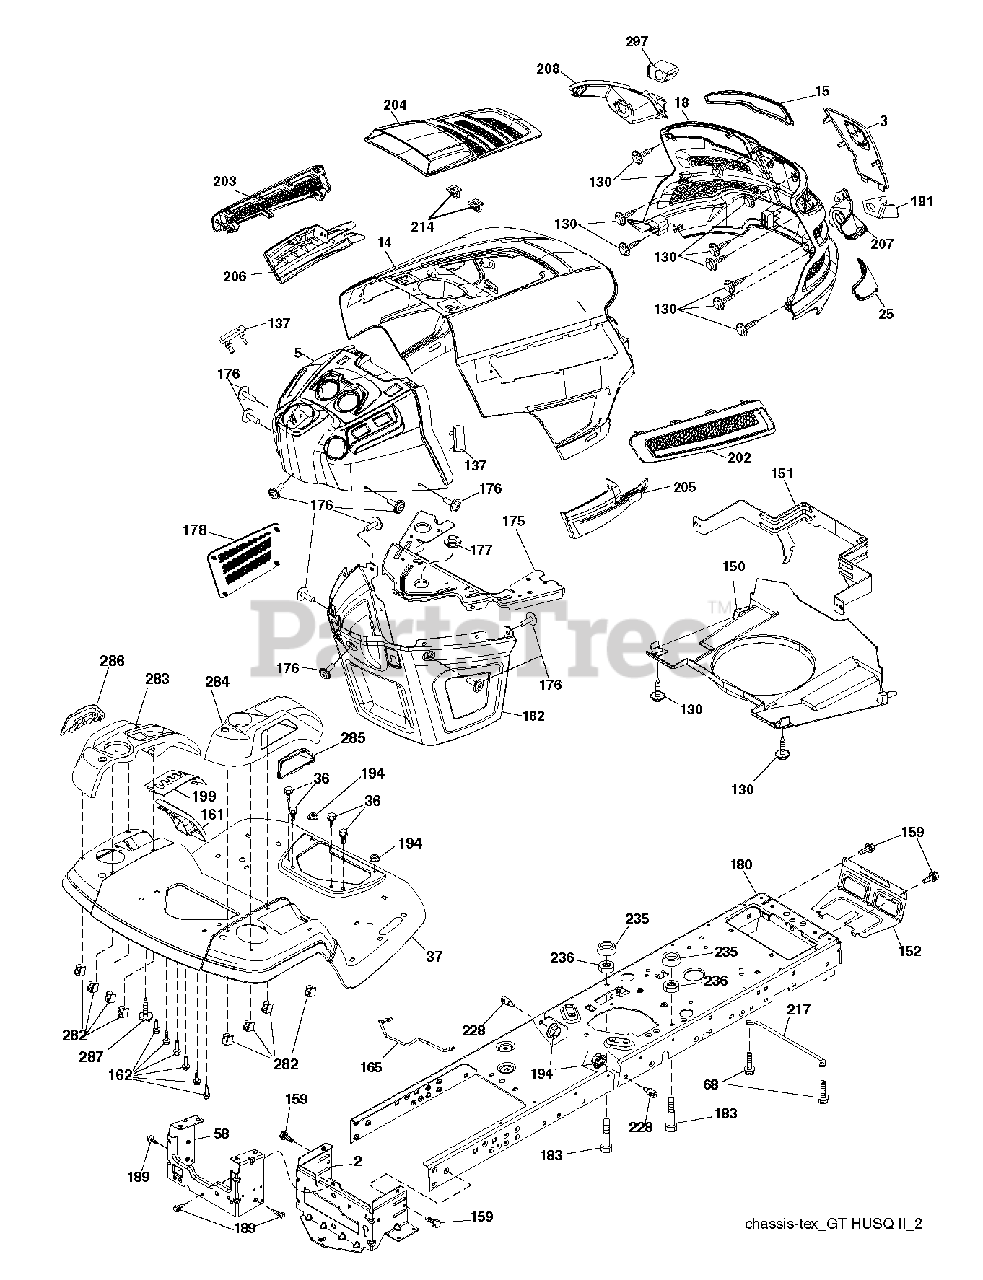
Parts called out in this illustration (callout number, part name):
2	DRAWBAR.1PC.NSTL
3	APPLIQUE.SUBASM.GT.HUSQ.II
5	DASH.UPPER.ASSY.GT2.DUAL
14	HOOD.ASM.HUSQVARNA.GT.TEX.422
15	LENS.HEADLIGHT.LH.GTII.2011
18	GRILLE.SUBASM.GT.HUSQ.II
25	LENS.HEADLIGHT.RH.GTII.2011
36	SCREW 5/16"
37	FENDER.TLT.FS.W/CPH/FW/RSF.ORN
58	DRAWBAR UPPER 2PC SMALL FENDER
68	SCREW LT
130	SCREW.#10 X 0.750.BOS
137	BUMPER DASH
150	AIR.DUCT.GTV.BLACK
151	BRACKET.PIVOT.HOOD.GT.HUSQ.II
152	SHIELD.BROWNING.PNT.GT.V2
159	SCREW, 3/8-16X3/4
161	WINDOW.FUEL.LT.HUSQ.TEX.498
162	SCREW.HI-LO.CONSOLE
165	SUPPORT.TANK.REAR.B/TE
175	PLATE.CROSSMEMBER.HUSQ
176	SCREW.#10-24X5/8.RN.QU
177	BUSHING, STEERING
178	CARGO.ASM.NET.TXGT.W/C
180	CHASSIS.STAMPING.LT/GT
182	DASH.LOWER.COMMON.12V.ADAPTOR
183	BOLT.5/16-18X1-1/4 FULL THD
189	SCREW
191	INSERT.REFLECTIVE.RH.HUSQ.GTII
194	NUT LOCK HEX FLANGE 5/16-18
199	PLATE.DECK.LIFT.HUSQ.LT
202	VENT.SIDE.RH.GT.HUSQ.II.
203	VENT.SIDE.LH.GT.HUSQ.II.498
204	VENT.TOP.HUSQ.GT2
205	SIDE.TRIM.RH.GT.HUSQ.II
206	SIDE.TRIM.LH.GT.HUSQ.II.GRAY
207	BEZEL LIGHT.RH.GT.II.MYLAR
208	BEZEL LIGHT.LH.GT.II.MYLAR
214	CLIP.RETAINER.TINNER.
217	ROD.PIVOT.HOOD
228	STUD.FASTNER.W/ANTI-ROTATE
235	SPACER FENDER
236	NUT.CENTERLOCK.5/16-
282	CLIP.RETAINER.CONSOLE.LT.HUSQ
283	CONSOLE.DECK.LIFT.R.SDFL.HUSQ
284	CONCOLE.CNTRL.PDL.HUSQ.LT.498
285	CONSOLE INSERT RH
286	CONSOLE.INSRT.LH.HUSQ.LT.BLACK
287	SCREW 1/4X20
297	INSERT.REFLECTIVE.LH.HUSQ.GTII
